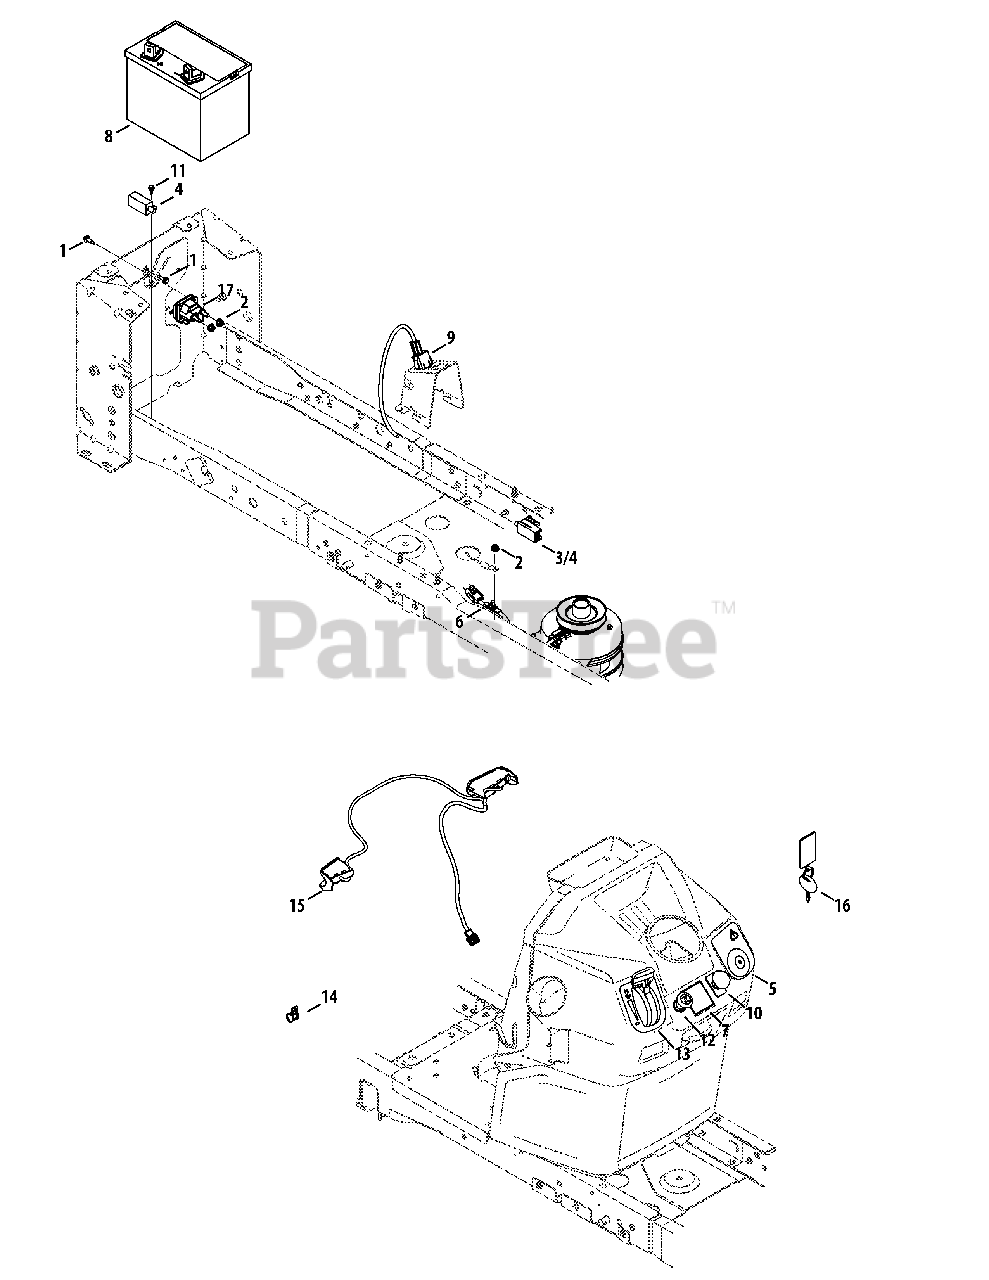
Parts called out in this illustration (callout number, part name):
1	Screw, M6-1 x .625
2	Nut, Flange Lock, 1/4-20, Nylon
3	Switch, 3-Pole (Man. PTO)
4	Switch, Interlock
5	Key Switch (Elec. PTO)
6	Jumper Harness (Elec. PTO)
7	Hour Meter
9	Dash Harness (Elec. PTO)
10	PTO Switch (Elec. PTO)
11	Shoulder Screw, #10-32 x .500
12	Choke Control
13	Throt Cable, 36.6"
14	Clamp, 1.0 Dia.
15	Headlight Harness Assembly
16	Key, Assembly
17	Solenoid
